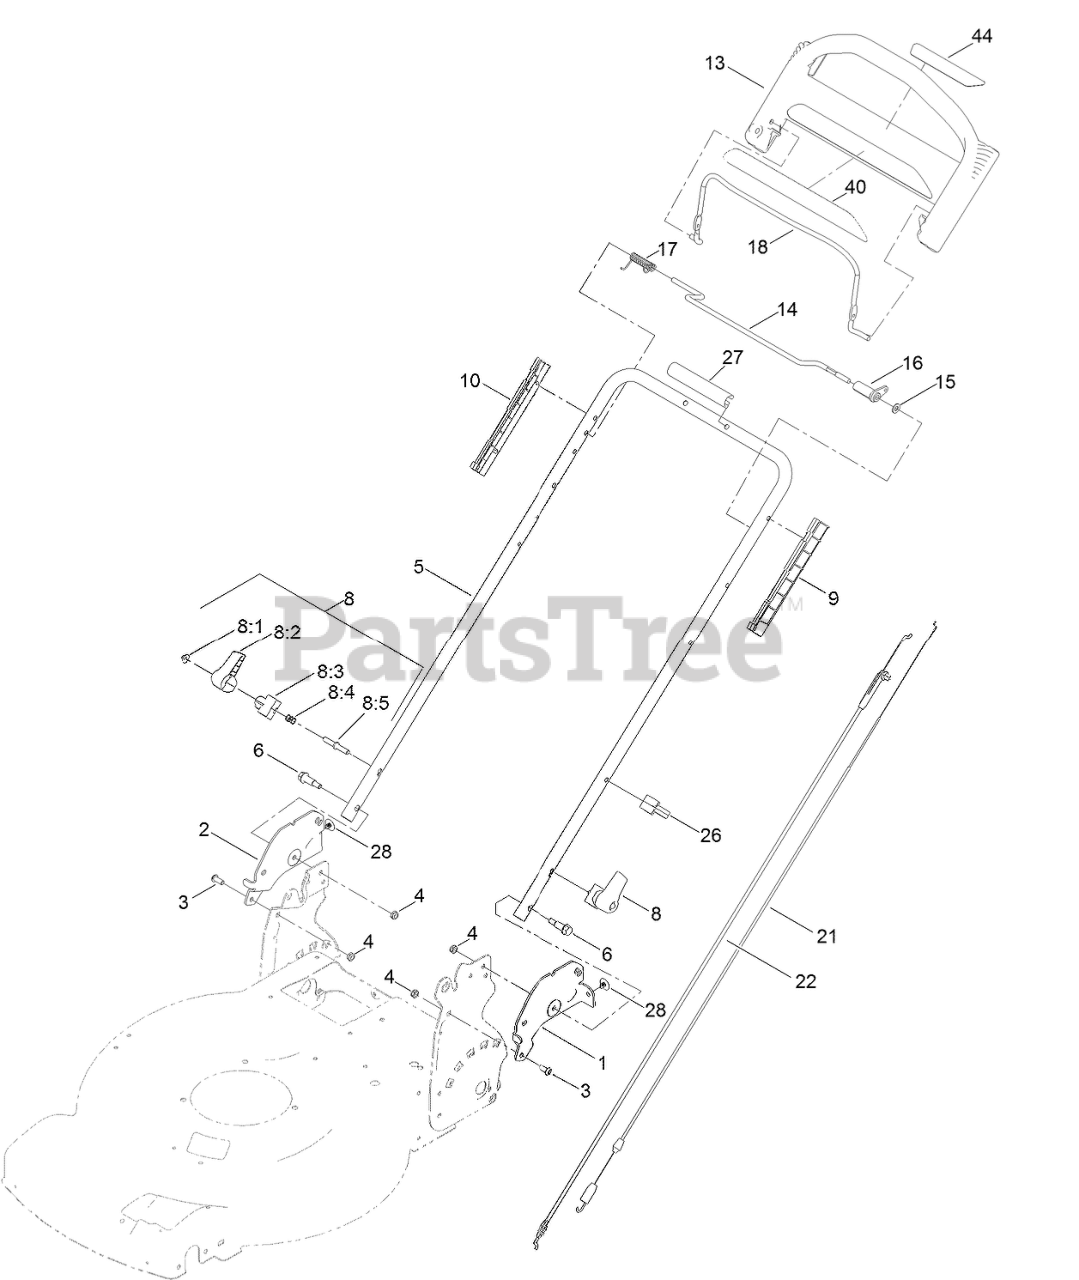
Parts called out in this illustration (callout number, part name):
1	PLATE-HANDLE, LH
2	PLATE-HANDLE, RH
3	SCREW-HSBH
4	NUT-HEX
6	BOLT-SHOULDER
8	QUICK RELEASE ASM
8:1	NUT-PUSH
8:2	LEVER-RELEASE
8:3	ANCHOR-SPRING
8:4	SPRING-COMPRESSION
8:5	ROD-RELEASE
9	GUIDE-LH
10	GUIDE-RH
13	HANDLE-CONTROL
14	BAR-CONTROL, TRACTION
15	WASHER-PLAIN
16	LEVER-TRACTION
17	SPRING-TORSION
18	BAIL-BRAKE
21	CABLE-TRACTION
22	CABLE-BRAKE
26	GUIDE-CABLE
27	HANDLE-COVER
28	CLIP-TREE
40	DECAL-HANDLE
44	DECAL-CONTROLS (60V)
